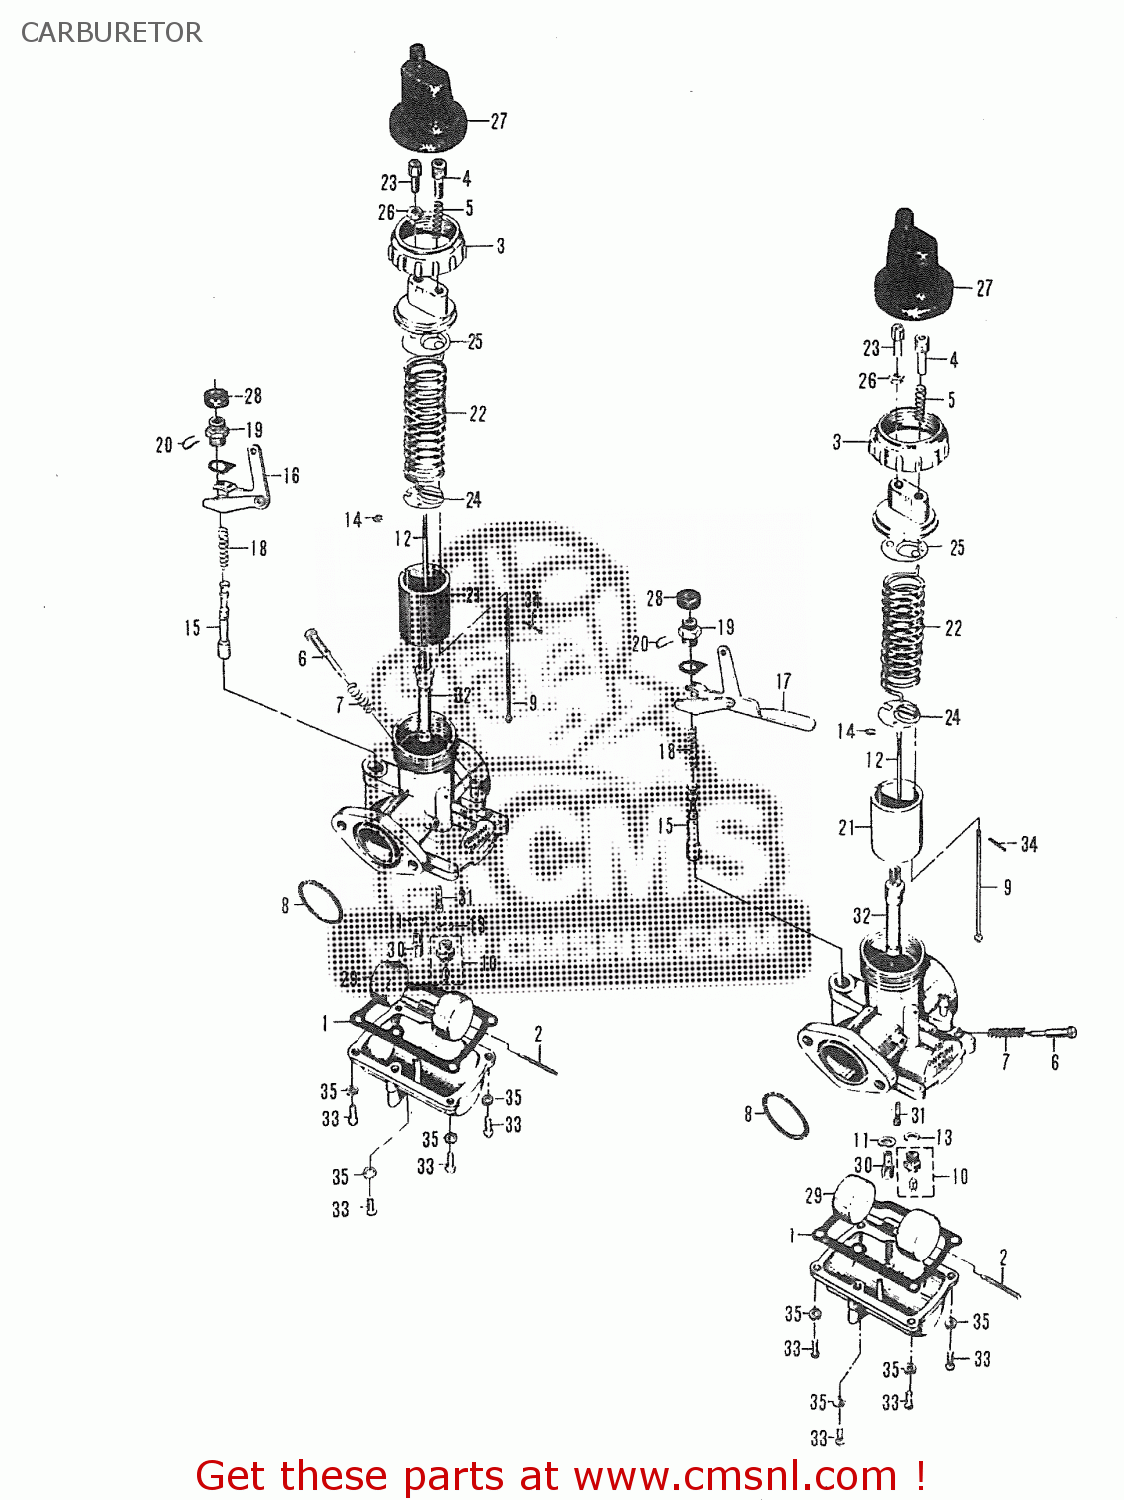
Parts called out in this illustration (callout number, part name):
1	GASKET,FLOAT CHAMBER (NAS)
2	PIN,FLOAT
3	MIXING CHAMBER CAP
4	SCREW,THROTTLE VALVE ADJUST
5	SPRING,THROTTLE SCREW
6	PILOT AIR ADJUSTING SCREW
7	PILOT AIR ADJUSTING SCREW SPRING
8	OUTLET O-RING
9	THROTTLE VALVE ADJUSTING ROD
10	VALVE ASSY,NEEDLE
11	WASHER
12	JET NEEDLE
13	GASKET,NEEDLE VALVE (NAS)
14	CLIP,NEEDLE
15	STARTER PLUNGER
16	RIGHT PLUNGER LEVER
17	LEFT PLUNGER LEVER
18	SPRING
19	STARTER PLUNGER CAP
20	STARTER PLUNGER FITTING SPRING
21	THROTTLE VALVE
22	THROTTLE VALVE SPRING
23	ADJUSTER,CABLE
24	SPRING GUIDE (A)
25	SPRING GUIDE (B)
26	NUT
27	CAP
28	CAP,PLUNGER
29	FLOAT
30	JET,MAIN 85
31	JET,PILOT
32	JET,NEEDLE(SN-6)
33	CROSS HEAD SCREW
34	COTTER PIN
35	LOCK WASHER
